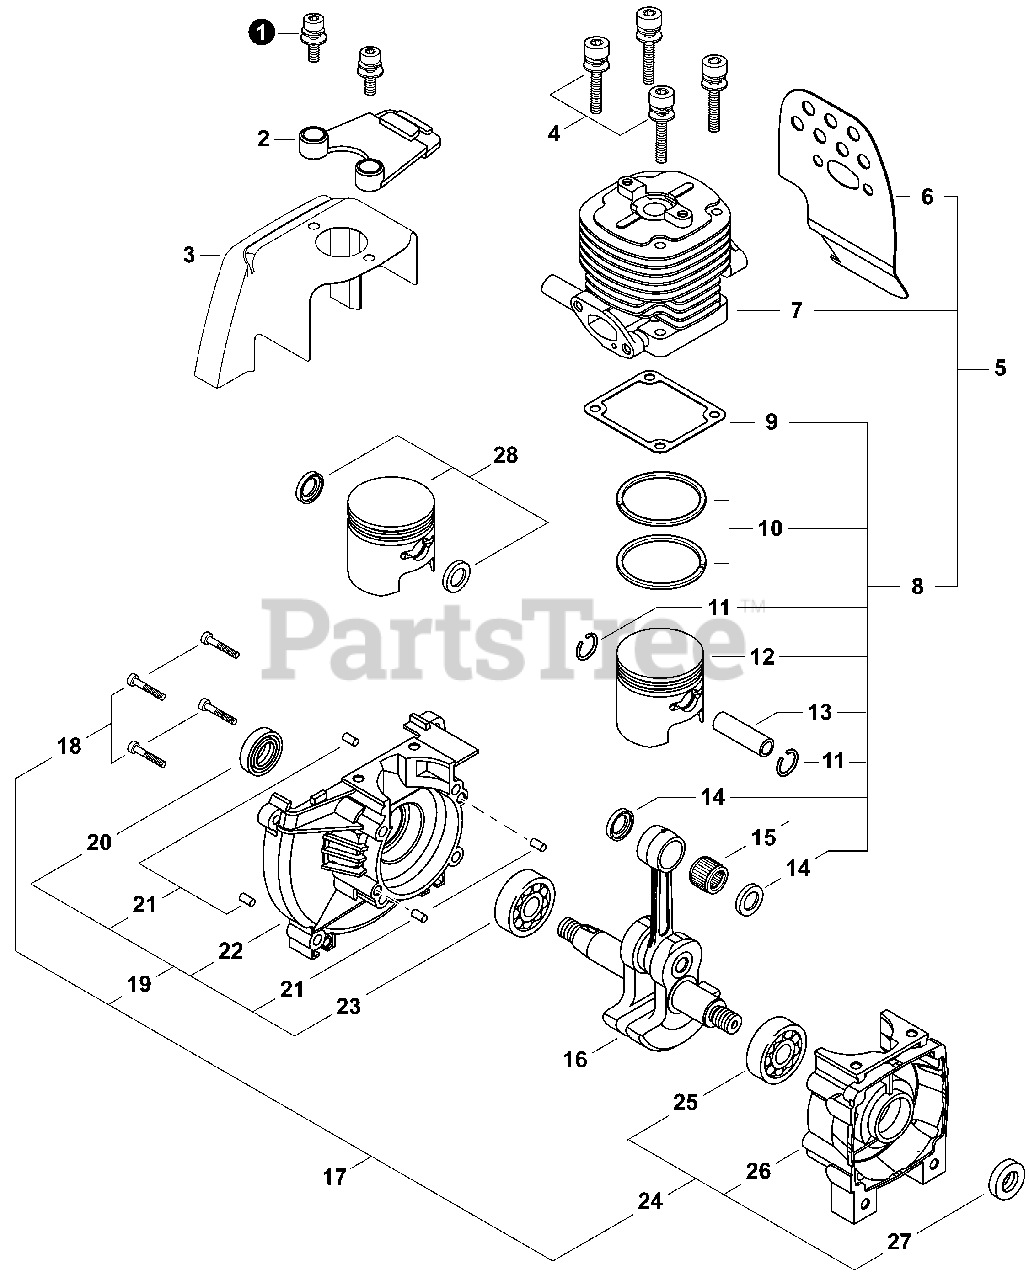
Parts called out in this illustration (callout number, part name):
1	BOLT M5×18
2	STAY, ENGINE COVER
3	COVER, ENGINE
4	BOLT M5×25
5	REBUILD KIT - ENGINE
6	HEAT SHIELD, EXHAUST
7	CYLINDER
8	PISTON KIT
9	GASKET, CYLINDER
10	RING, PISTON
11	RING, SNAP
12	PISTON
13	PIN, PISTON
14	WASHER, THRUST 11
15	BEARING, NEEDLE 11
16	CRANKSHAFT ASSY
17	CRANKCASE ASSY
18	BOLT 5×30
19	CRANKCASE ASSY, M
20	SEAL, OIL 16
21	PIN, LOCATING 5×10
22	CRANKCASE M
23	BEARING, BALL 6202 C3
24	CRANKCASE ASSY, S
25	BEARING, BALL 6202 C3
26	CRANKCASE S
27	SEAL, OIL 16
28	PISTON SET
